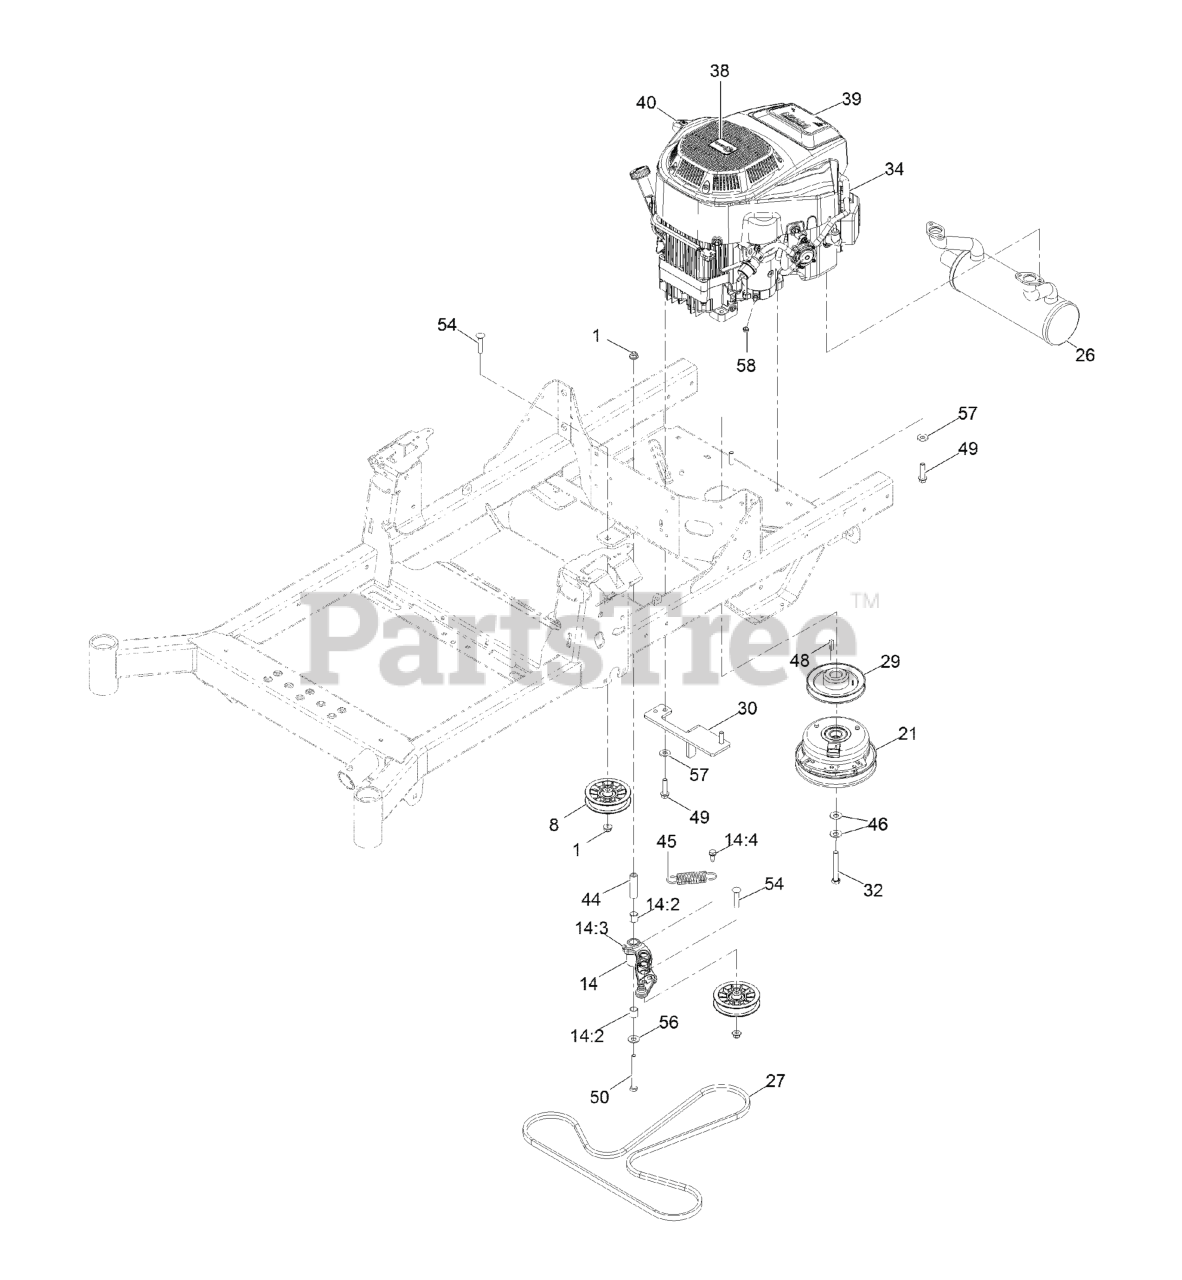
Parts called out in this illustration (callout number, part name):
1	NUT-HF, NI
8	PULLEY-FLAT IDLER
14	IDLER ARM ASM
14:2	SLEEVE-BEARING
14:3	FITTING-GREASE, 90 DEG
14:4	SCREW-THD ROLL, HWH
21	CLUTCH 1.00
26	MUFFLER
27	BELT-V
29	SHEAVE-ENGINE
30	ANCHOR-CLUTCH
32	SCREW-HH W/LOCTITE
34	ENGINE-2P77F
39	DECAL-708CC V-TWIN ENGINE
40	DECAL-DRAIN, OIL
44	BUSHING-PIVOT, IDLER
45	SPRING-EXTENSION
46	WASHER-SPRING
49	SCREW-HWH
50	SCREW-HH
54	SCREW-CARR
56	WASHER-FLAT
57	WASHER-BELLEVILLE
